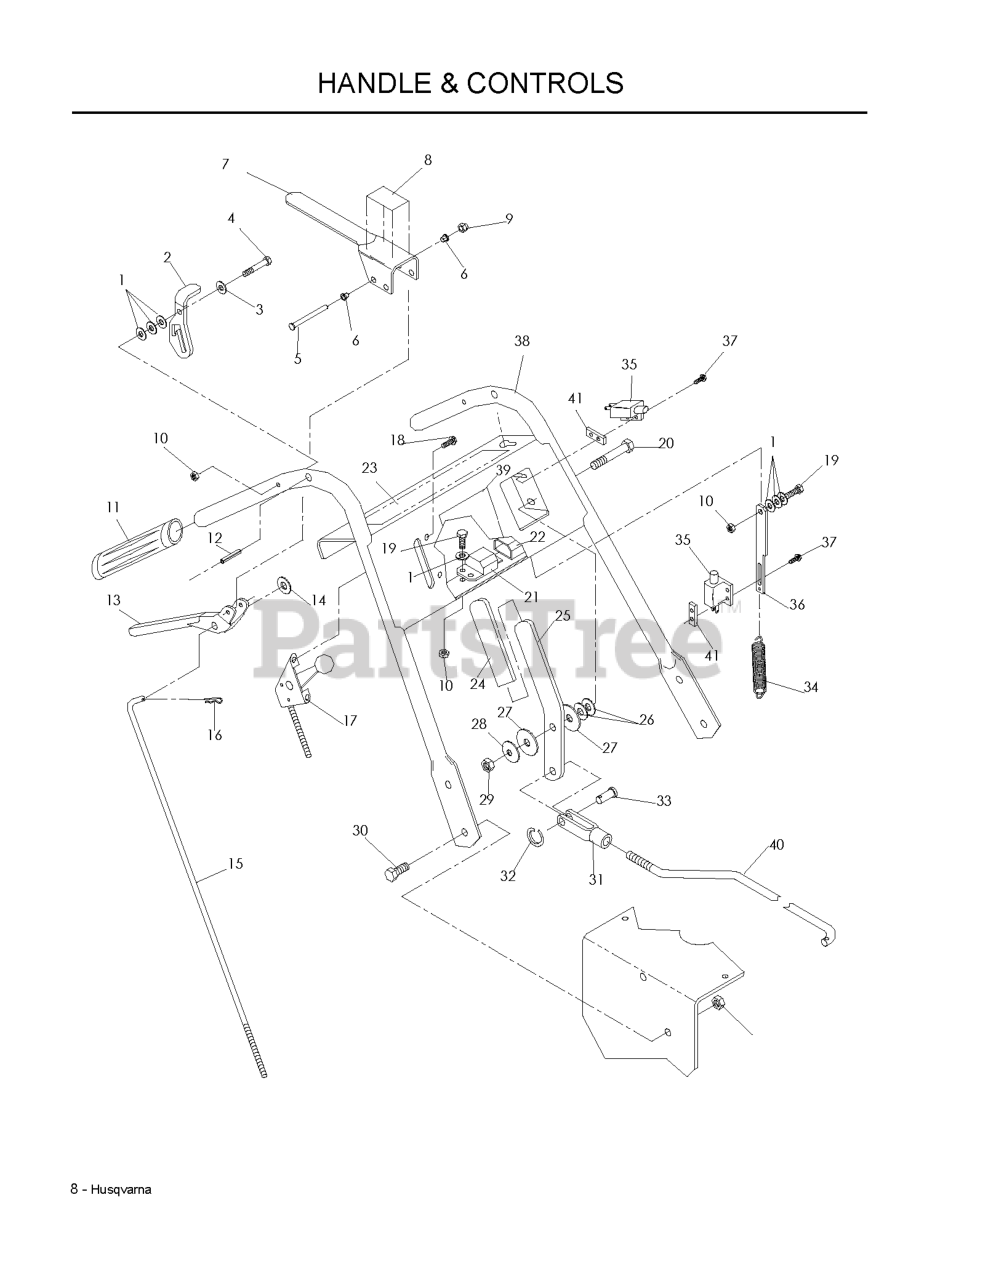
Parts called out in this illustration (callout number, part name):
1	WASHER 1/4 SAE
2	LATCH, RT.THUMB W/GRIP
2	LATCH LT THUMB W/GRIP
3	WASHER, WAVE SPRING
4	BOLT 1/4C X 1 3/4
5	PIN CLEVIS
7	LEVER OPC W/GRIP
8	DECAL, THUMB LATCH
10	NUT 1/4C CENTER LOCK
11	GRIP HANDLE
12	ROLL PIN 5/16 X 1.125
13	DRIVE LEVER
14	WASHER 5/16 FLAT
15	TRACTION ROD
16	HAIRPIN #2
17	THROTTLE CONTROL W/BALL KNOB
17	THROTTLE CABLE W/ BALL KNOB
18	HWST 1/4C X 3/8
19	HCS 1/4C X 3/4 HCS
20	HCS 3/8C X 1 1/2
22	HANDLE HARNESS
22	HANDLE HARNESS, KAW
23	DECAL, OPERATING
26	WASHER 3/8 FLAT
27	WASHER, FIBER
28	CONE WASHER
29	NUT 3/8C CENTERBLOCK
30	HCS 3/8-16X1.GRD.5.ZD
31	YOKE-3/8-24 PLTD
33	CLEVIS PIN 3/8 X 1 1/8
36	LINKAGE, O P
37	SCREW #10-24 X 5/8
38	HANDLE, UPPER W/DECALS
39	DECAL, OPERATION
41	TAPPED PLATE
